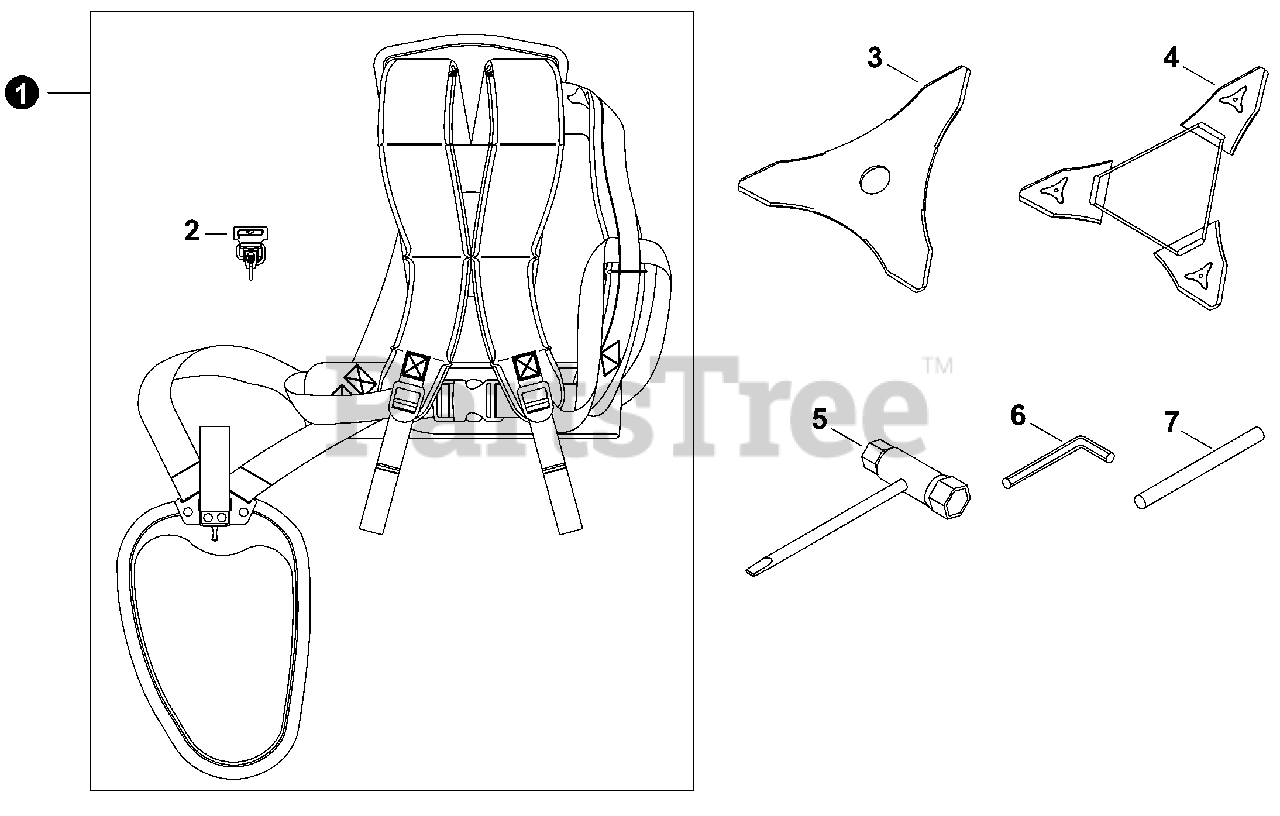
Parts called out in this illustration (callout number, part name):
1	HARNESS, BRUSHCUTTER
2	HOOK, SNAP
3	BLADE, 10" 3-TOOTH
4	SCABBARD
5	T-WRENCH 17x19 L200
6	WRENCH, ALLEN
7	TOOL, LOCKING 5x120 MM
